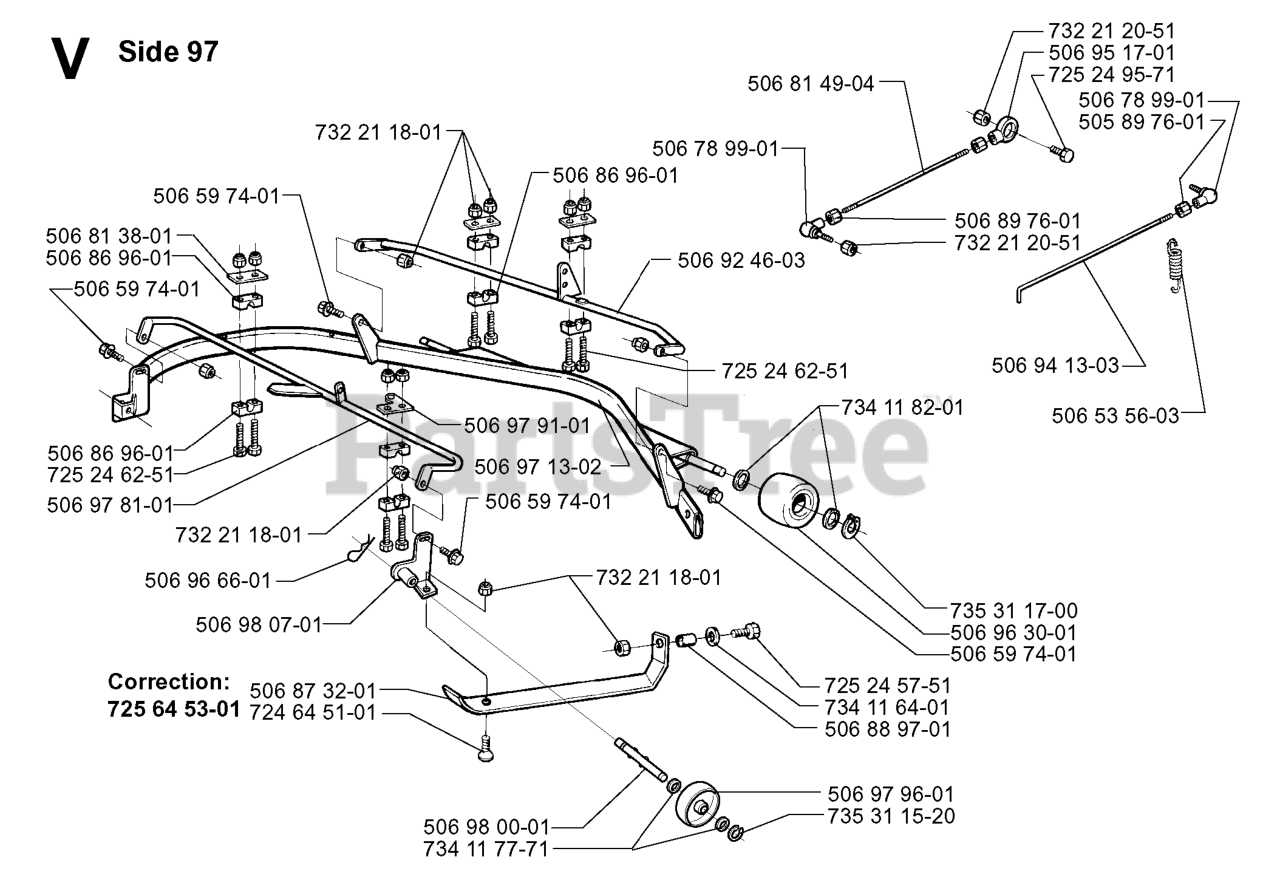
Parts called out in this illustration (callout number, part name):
2	MUFFLER.TWIN.CYL.LOW.TONE
9	KEEPER.BELT.ENGINE.4.2
11	CLUTCH MZ ZTR GT.48/54"1.125"
12	PULLEY ENGINE
14	TUBE, DRAIN OIL ASM.
15	TANK.ASM.4.GAL.EPA.ONE.PORT
18	CAP.ASM.FL.RITCH.3"E10.SYM.498
20	THROTTLE CABLE
21	SCREW.#10 X 0.750.BOS
22	CONTROL.CHOKE.ERGO.PUSH-IN.BLA
28	LINE.FUEL.64"REAR.EMIS
29	KIT.SPARK ARRESTOR 794945 B&S
37	HOSE CLAMP
42	LOCKWASHER
45	NUT
62	SHIELD.HEAT.MUFFLER
70	TUBE.EXHAUST.LH.FR961/FR730
71	TUBE.EXHAUST.RH.FR961/FR730
85	BOLT HEX 7/16-20 X 3.75 GR. 5
86	NUT.HEX.FLANGE.TOPLOCK
87	BOLT.5/16-18UNCX1.W/SEMS.BLK
90	SCREW 3/8-16X1
91	BUSHING.1.375OD
92	SCREW 3/8-16X1
110	VALVE.ASM.ANTI-SLOSH
